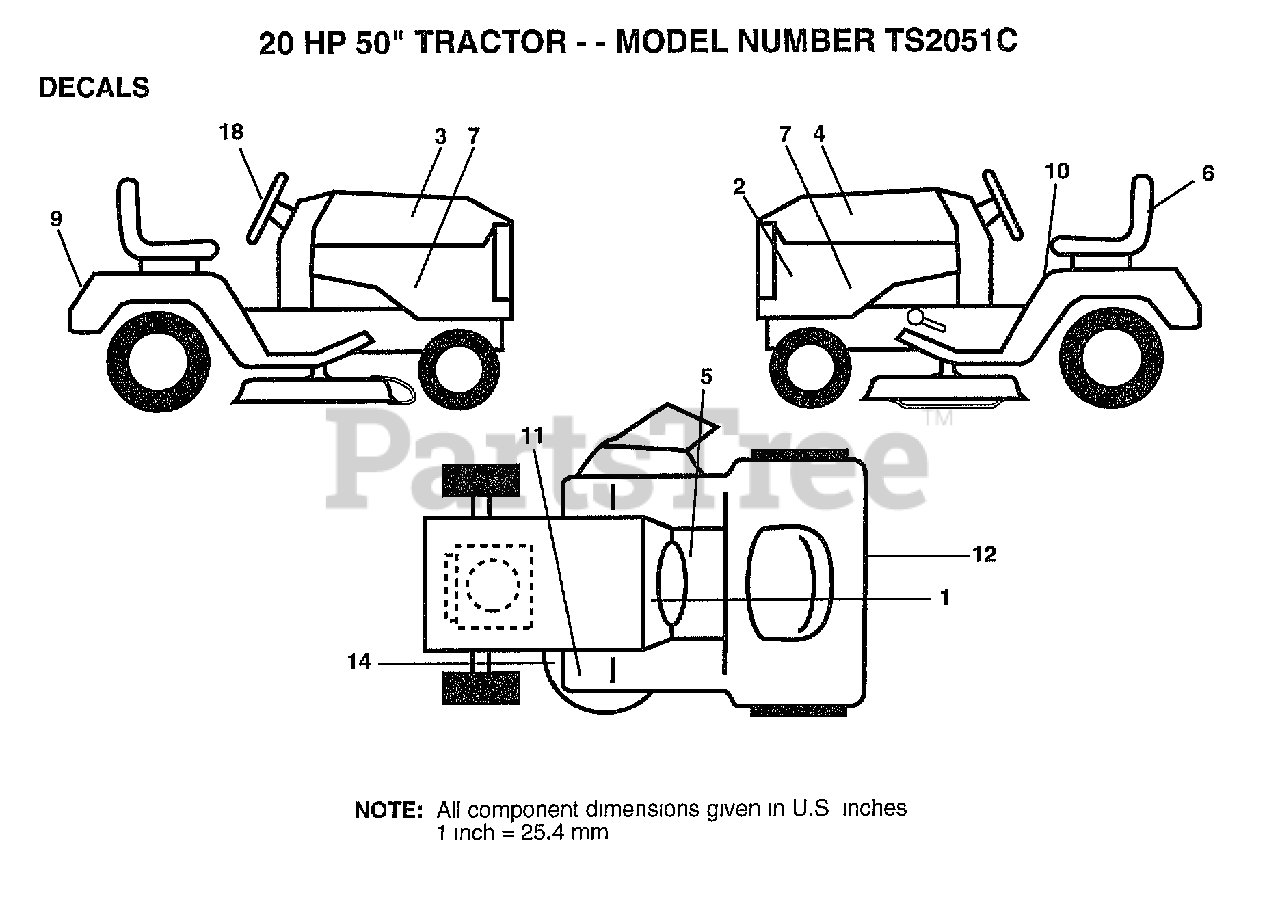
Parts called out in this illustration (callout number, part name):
1	DECAL.DASH.INST.
2	NAMEPLATE.HUSK.LG
3	DECAL.HD.RH.20/50
4	DECAL.HD.LH.20/50
7	DECAL.PNL.SIDE.20
9	DECAL.FEND.YT/GT
10	DECAL
14	"DECAL.V.BELT.44"""
18	DECAL.INS.WHL.STG
